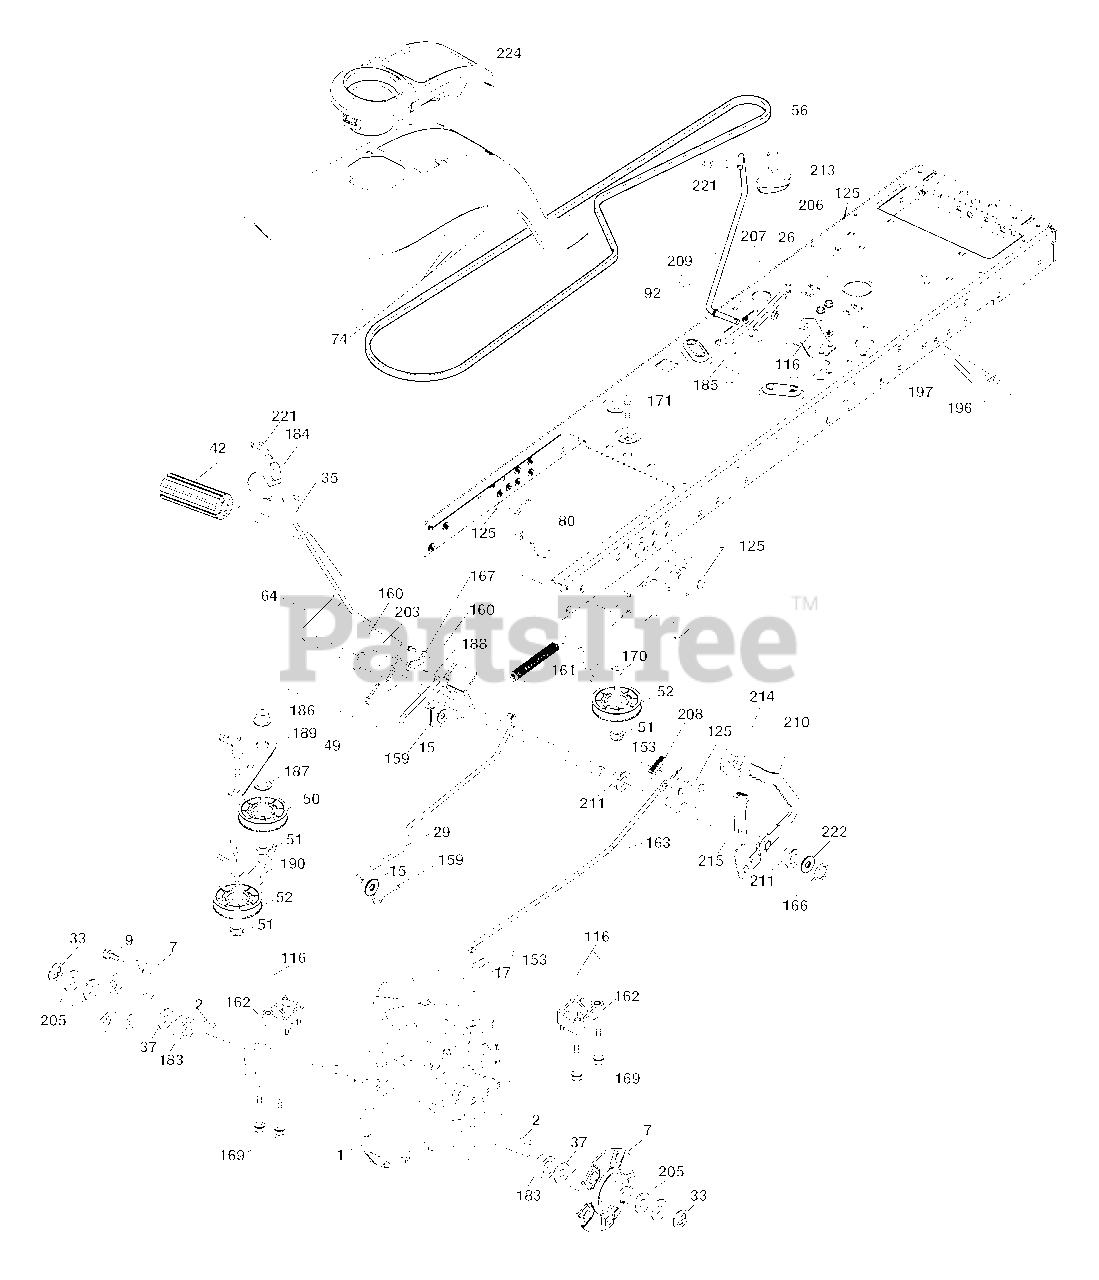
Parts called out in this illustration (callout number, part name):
2	Key 1.87 x 2.500
7	Hub Asm. Wheel
9	Bolt Hub Wheel
15	Washer 13/32 x 13/16 x 16 Ga.
17	Spring, Brake
26	Spring Return Cruise
29	Rod, Brake
33	Ring E #5133-75
35	Rod, Brake, Park
37	Washer 25/32 x 1-1/4 x 16 Ga.
42	Cover, Foot Pedal
49	Bolt
50	Pulley Idler Flat
51	Lock Nut 3/8-16
52	Idler V-Groove 910" Offset
56	V-Belt, Drive
64	Shaft Asm. Pedal Brake Control
74	Screw 1/4 x 1/2
80	Bracket Strp. Trq.
92	Bolt Fin Hex 5/16-18 unc x 1.25
116	Nut Lock Hex Flange 5/16-18
125	Screw 5/16-18 x 3/4
153	Retainer Spring 1"
159	Pin Cotter 1/8 x 3/4
160	Retainer Clip
161	Spring, Return, Clutch
162	Spacer Trans.
163	Rod Control Cruise
166	Nut Push .625
167	Latch Brake Parking
169	Bolt Hex Flngd. 5/16-18 x 3.75
170	Keeper Belt Centerspan
171	Bolt
183	Spacer Split 800 x 350.
184	Handle Parking Brake
185	Bolt
186	Spacer Retainer
187	Washer
188	Link Clutch Ground Drive
189	Bellcrank Ground Drive
190	Keeper Bellcrank Ground Drive
196	Screw 3/8-16 x 1
197	Bracket Clutch Anti-Rotation
203	Washer 11/32 x 11/16 x 16 Ga.
205	Washer 25/32 x 1-5/8 x 16 Ga.
206	Bracket Mount Latch Cruise
207	Latch Control Cruise
208	Gear Sector Control Cruise
209	Rod Control Cruise
210	Rocker Asm. Pedal Control
211	Bearing Nylon Blk .629
213	Knob Control Cruise
214	Pedal Forward
215	Pedal Reverse
221	Retainer Spring Clip Handle
222	Washer 21/32 x 1-1/4 x 10 Ga.
224	Console Toolbox
